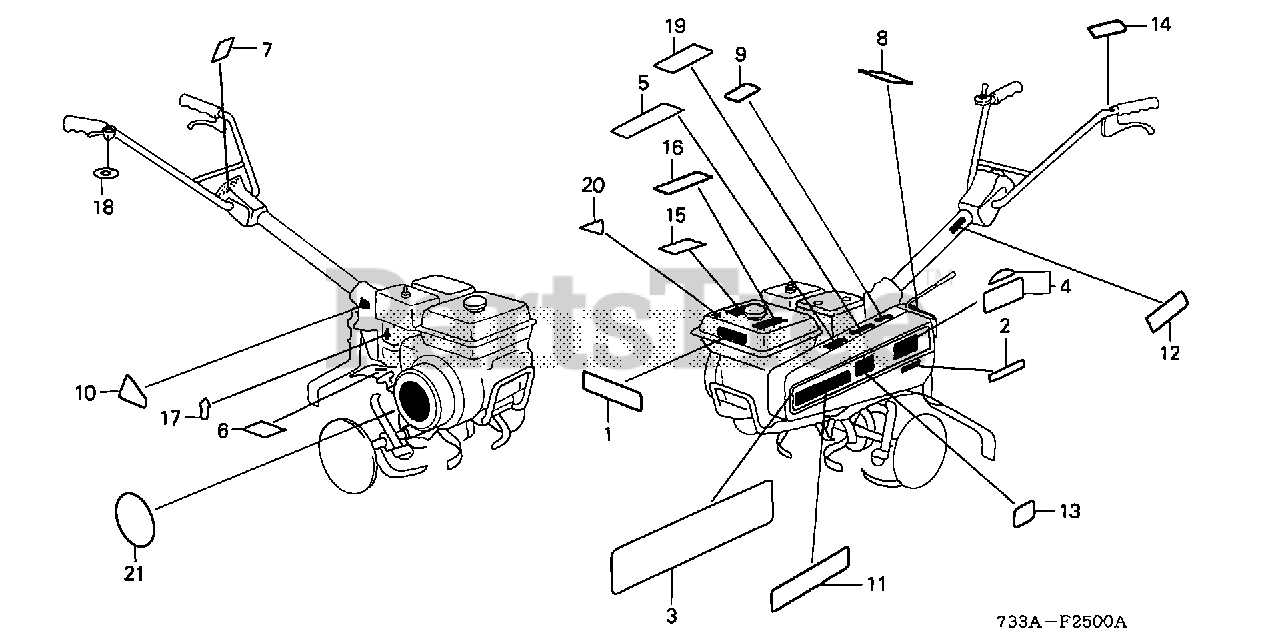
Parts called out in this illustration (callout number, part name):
1	MARK, HONDA EMBLEM (12 (HONDA)
2	MARK, L. STRIPE (F501)
4	MARK, SIDE EMBLEM
5	LABEL, BELT WARNING
6	LABEL, TINE DANGER
7	MARK, ENGINE SWITCH (ENGLISH)
11	EMBLEM (13 (HONDA)
14	MARK, CLUTCH INDICATION
15	LABEL, OPERATOR WARNING
17	MARK, CHOKE
19	MARK, EX. CAUTION (A)
21	PLATE, EMBLEM
